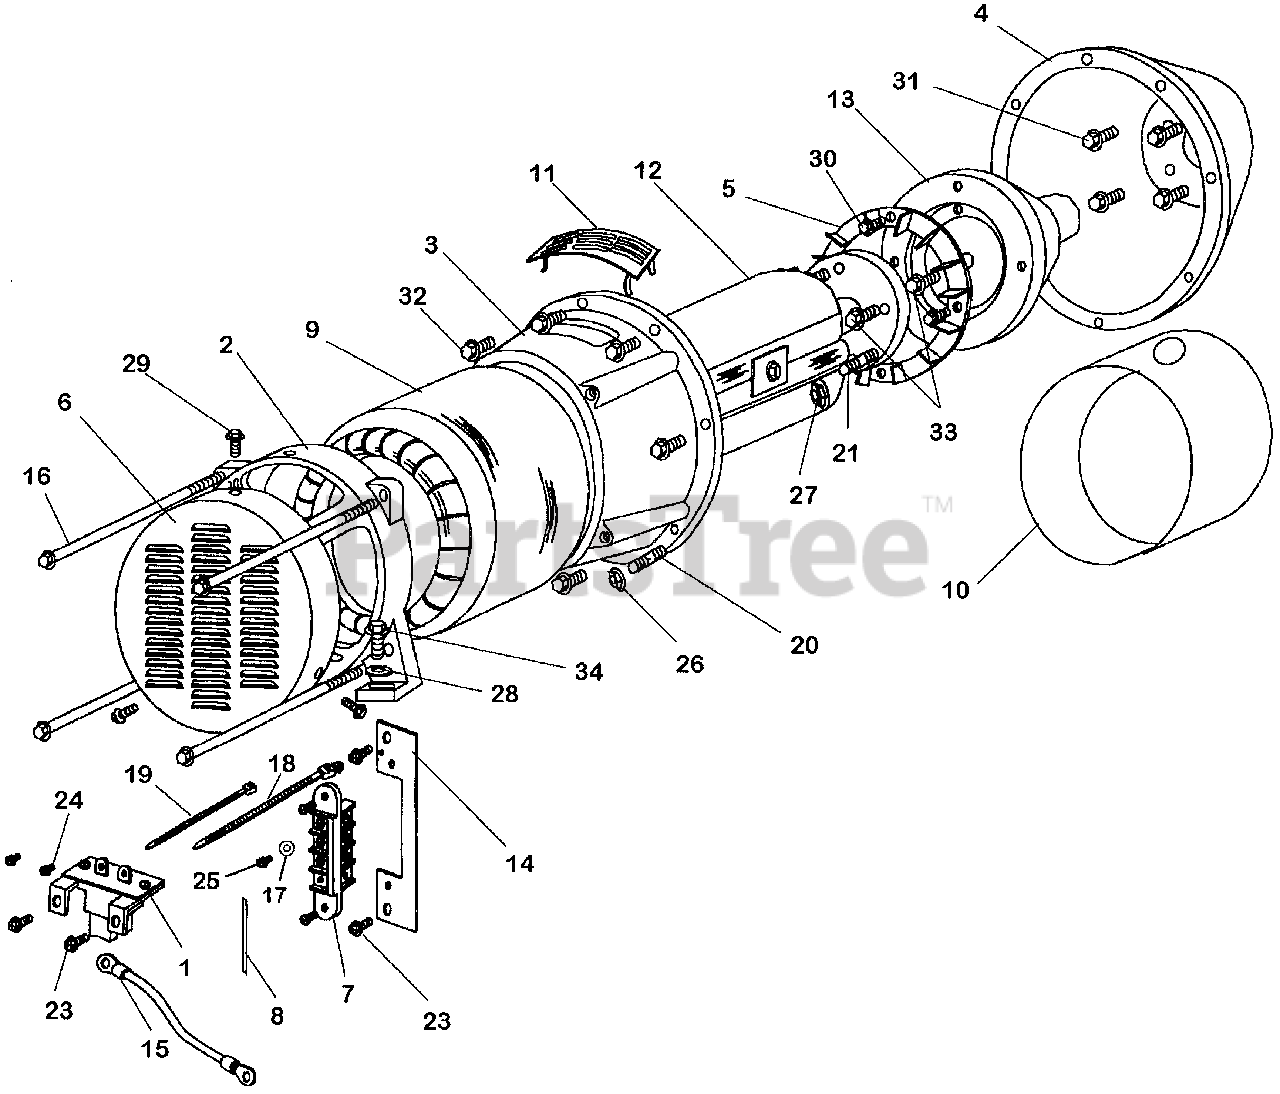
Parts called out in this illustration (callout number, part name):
1	BRUSH ASSY.
2	HOUSING, RR.
3	HOUSING, FR.
4	HOUSING, FR.
5	FAN, GENERATOR COOLING
6	COVER, GENERATOR END *NH105* (MAT BLACK)
7	TERMINAL, A.C. OUT
9	STATOR ASSY.
10	COVER, STATOR
11	PLATE, HOUSING
15	WIRE, GROUND
16	BOLT, FLANGE (10X170)
17	WASHER, SPRING (6MM)
18	TIE, CABLE (NATURAL 225X5.0)
19	TIE, CABLE
20	BOLT 2, STUD (8X32)
21	BOLT, STUD (10X40)
22	BOLT-WASHER (5X20)
23	BOLT-WASHER (6X16)
24	SCREW, PAN (4X8)
25	SCREW, PAN (6X8)
26	NUT, FLANGE (8MM)
27	NUT, FLANGE (10MM)
28	WASHER, PLAIN (12MM)
29	BOLT, FLANGE (6X12) Use up to Engine SN 1543277.
30	BOLT, FLANGE (8X20)
31	BOLT, FLANGE (8X25)
32	BOLT, FLANGE (8X35)
33	BOLT, FLANGE (10X35)
34	BOLT, FLANGE (12X35)
